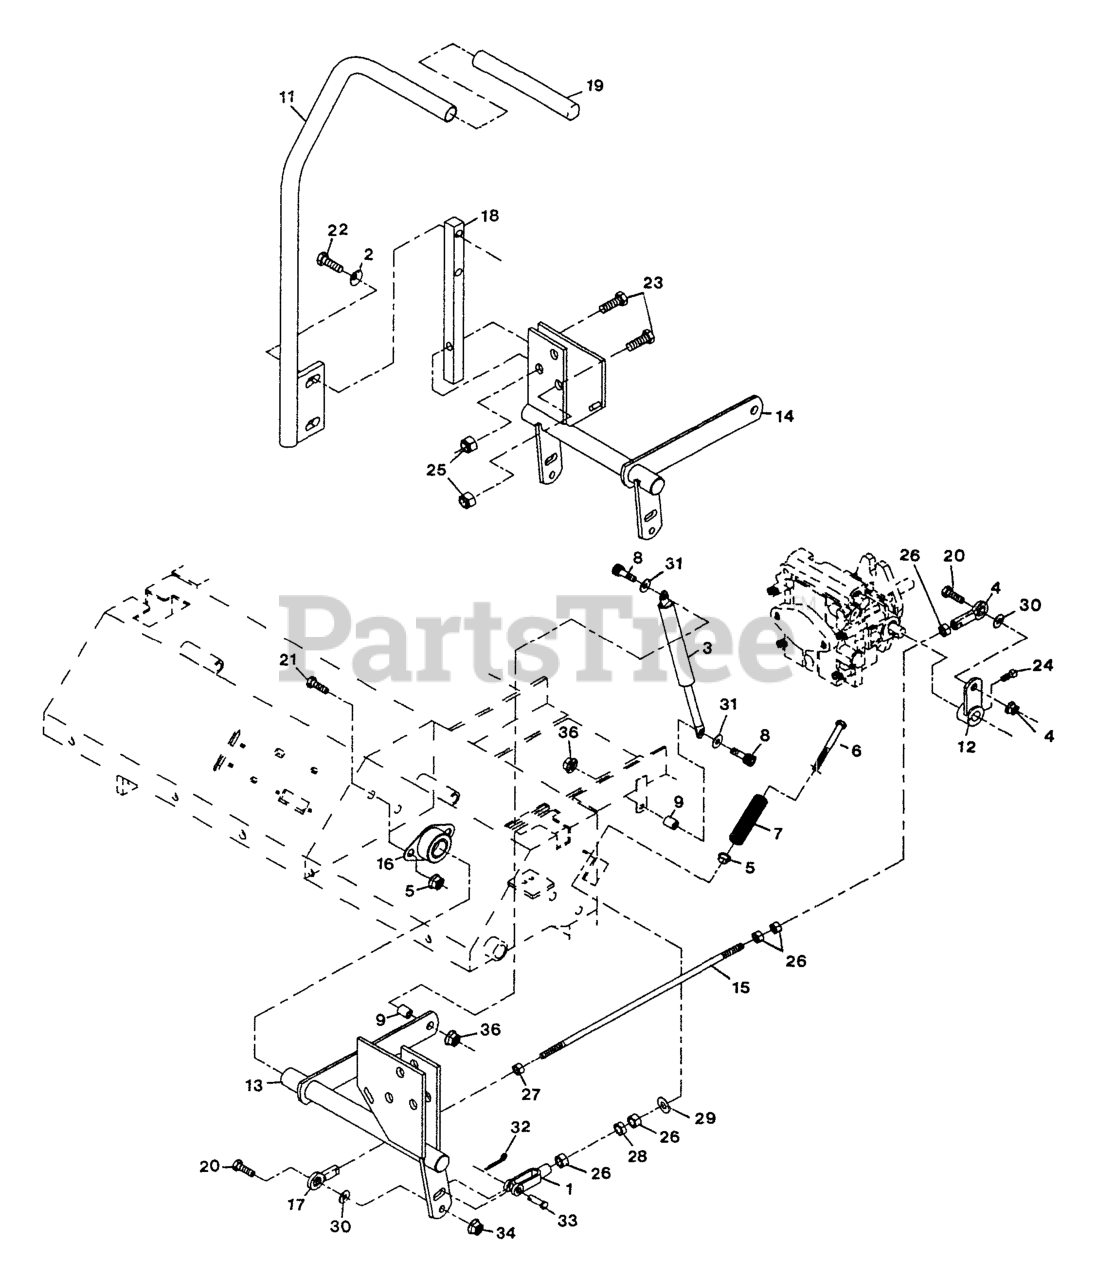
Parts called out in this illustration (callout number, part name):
1	YOKE-ADJUSTABLE
4	BALLJOINT-RH
5	BUSHING-FLANGED
6	BOLT-RETURN, NEUTRAL
7	SPRING-RETURN, NEUTRAL
8	SCREW-HSH
16	BEARING-FLANGE, SIDE
17	BALLJOINT-LH
18	ARM-CONTROL, SHAFT
19	GRIP-CONTROL, MOTION
24	SCREW-SET
33	PIN-CLEVIS
